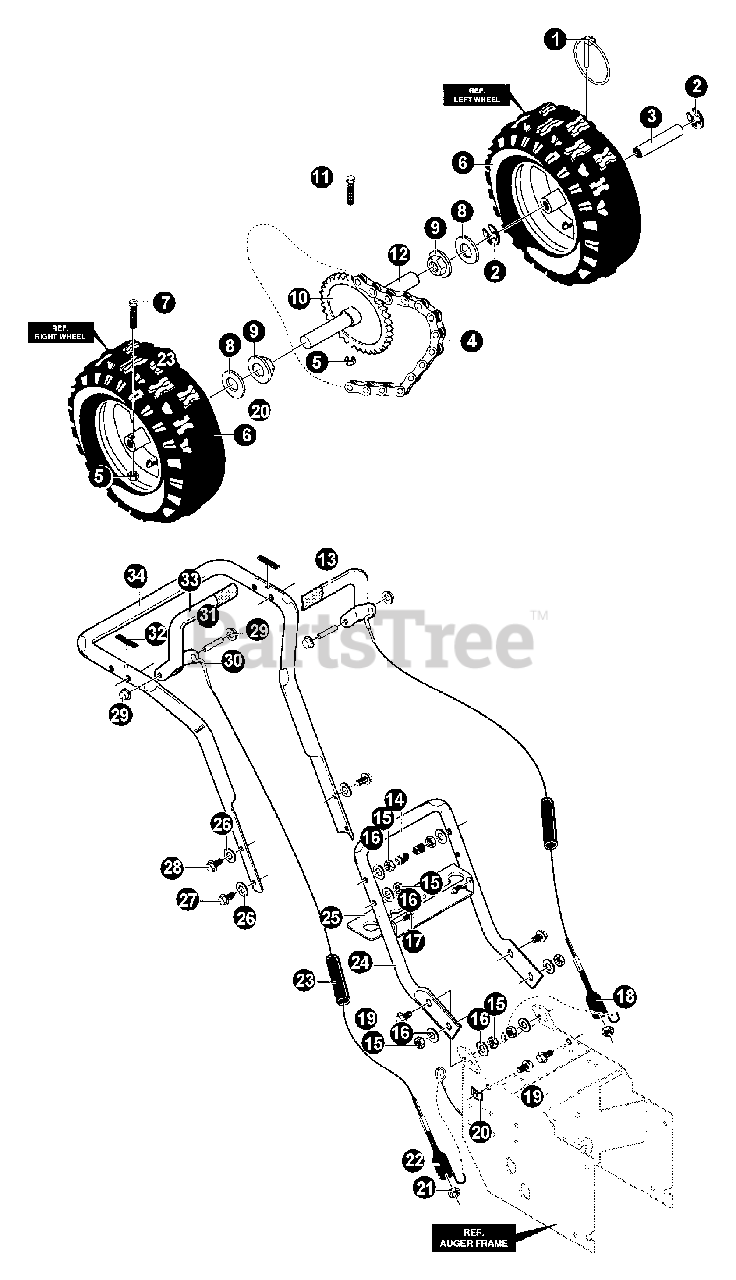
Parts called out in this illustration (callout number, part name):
1	PIN, KLIK
2	RING, RETAINING
3	BUSHING, WHEEL 4" LG
4	CHAIN, ROLLER #42X40P
5	NUT - 1/4-20
6	WHEEL ASSY
7	SCREW - 1/4-20 X 1.75"
8	WASHER
9	BEARING, FLANGE
10	SPROCKET KIT
11	SCREW - 1/4-20 X 2.25"
12	SHAFT, AXLE
13	LEVER KIT
14	STOP, RED PLASTIC
15	NUT - 5/16-18
16	LOCKWASHER
17	SCREW - 1/4-20 X 3/4"
18	SPRING
19	SCREW - 5/16-18 X 1"
20	PUSHNUT - 5/16"
21	NUT - 1/4-20
22	SPRING, AUGER CLUTCH
23	BOOT, CLUTCH SPRING
24	HANDLE - LOWER
25	BRACKET, GEAR SELECTOR
26	WASHER
27	SCREW - 5/16-18 X 2"
28	SCREW - 5/16-18 X 2-3/4"
29	PUSHNUT
30	CABLE, CLUTCH
31	PIN, PIVOT
32	BUMPER, RECT
33	LEVER KIT
34	HANDLE - UPPER
